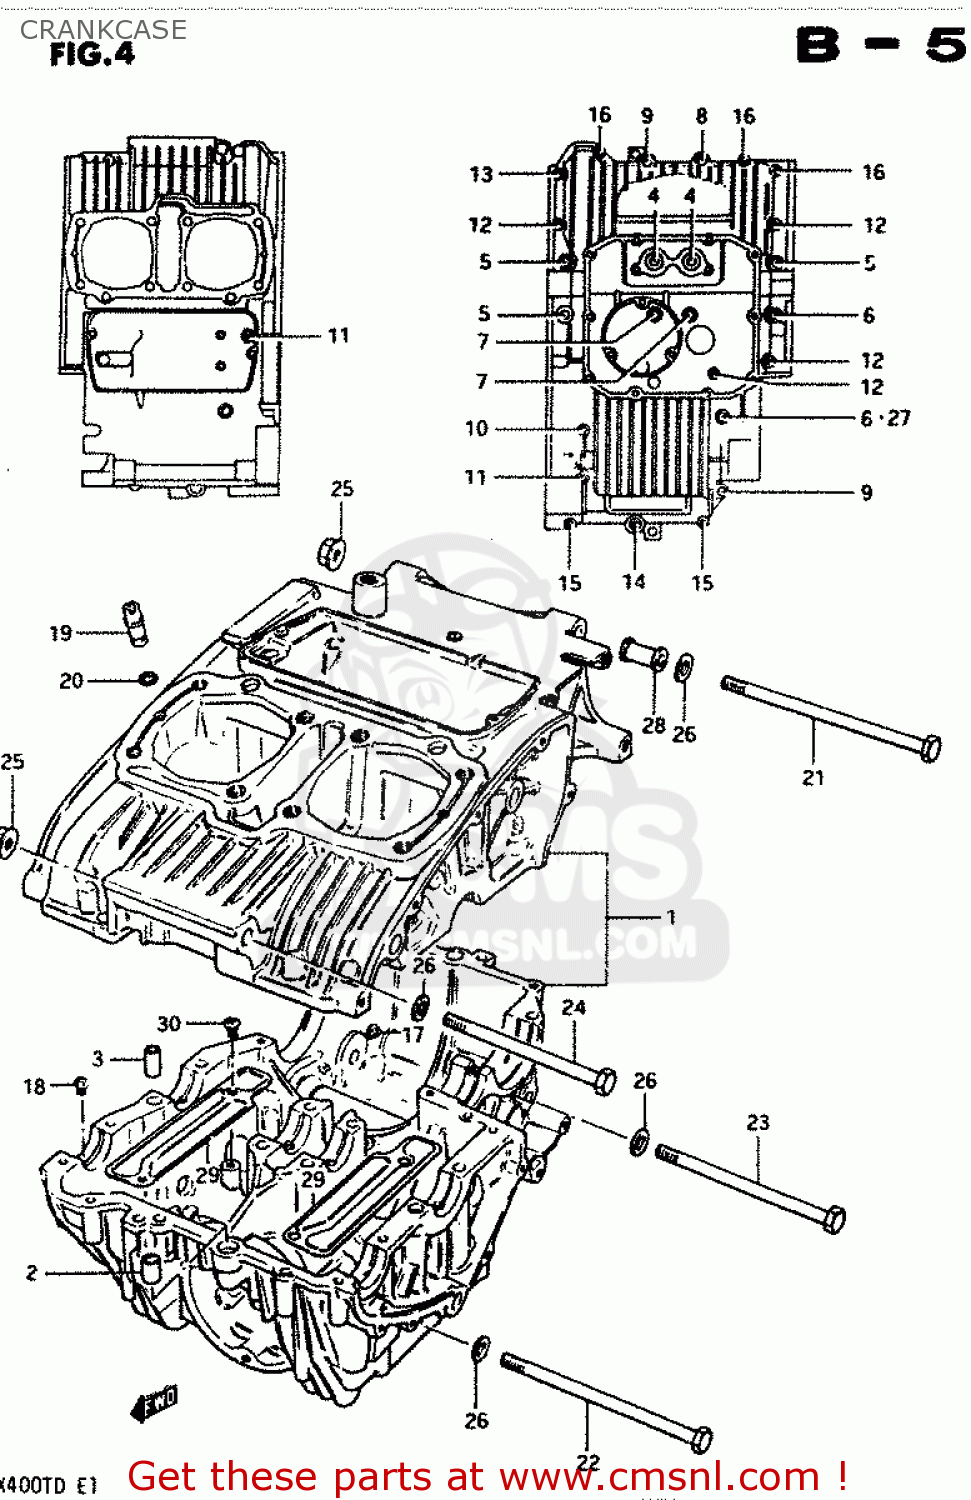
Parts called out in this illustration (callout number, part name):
1	CRANKCASE ASSEMBLY
2	PIN(10.4X13X22)
3	PIN (11X20)(SUS)
4	BOLT
5	BOLT
6	BOLT
7	BOLT
8	BOLT 8X65
9	BOLT (8X45)
10	BOLT(6X125)
11	BOLT
12	BOLT (6X90)
13	BOLT (6X70)
14	BOLT 6X65
15	BOLT ,6X50
16	BOLT,UNDER
17	JET,AIR
18	JET
19	JET
20	O RING(D:1.05,ID:3.1)
21	BOLT
22	BOLT
23	BOLT
24	BOLT
25	NUT 10MM
26	WASHER
27	GASKET 8.2X14X1 (NAS)
28	SPACER,ENGINE MOUNT
29	PLATE,OIL SEPARATOR
30	SCREW
